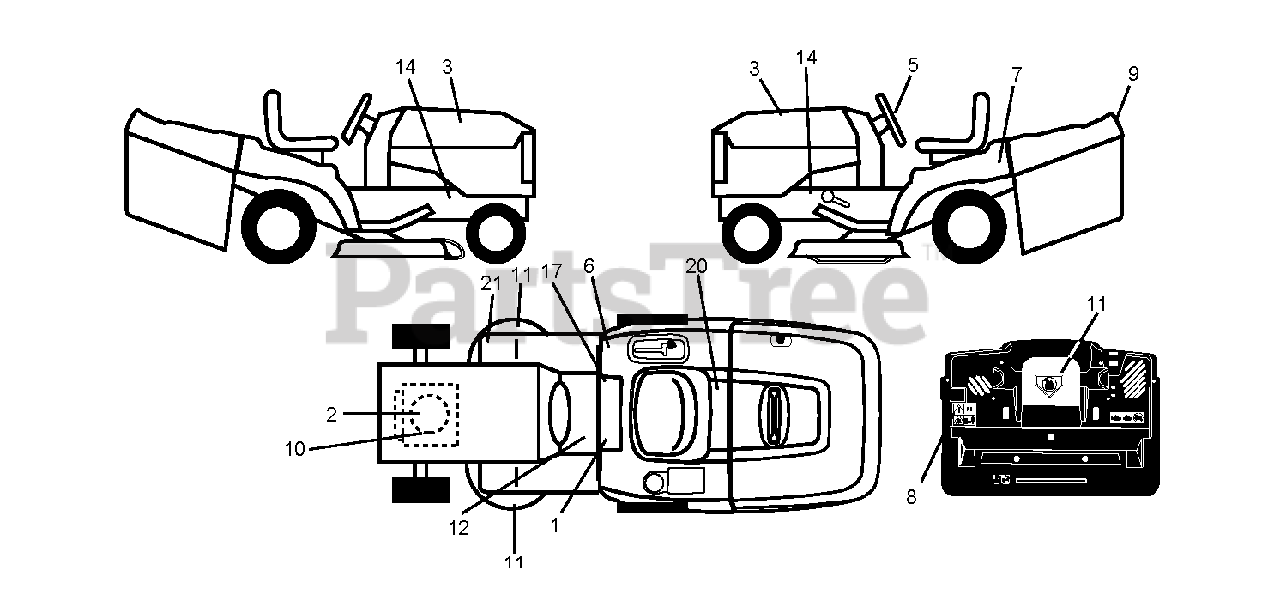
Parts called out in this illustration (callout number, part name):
6	Decal, 100 DB/CE
7	DECAL BTRY SYMBOLS
11	DECAL.INTERNATIONL.CUTFINGER
17	DECAL PARK BRAKE
20	DECAL.BYPASS.FENDER.CRD.LT.YT
